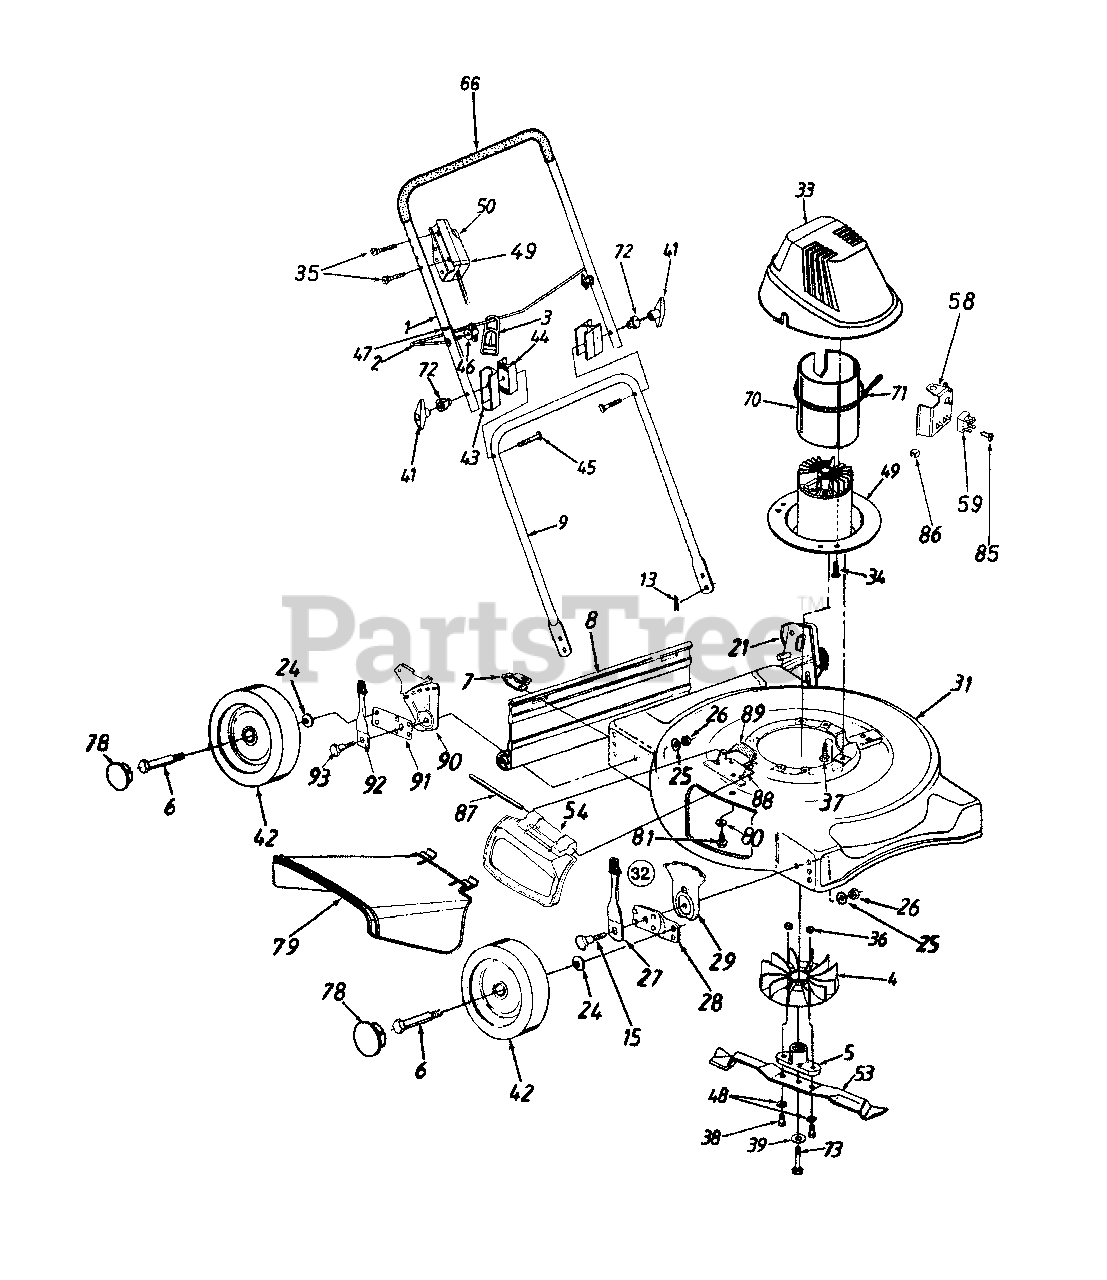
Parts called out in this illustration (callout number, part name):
3	Strain Relief Cord
5	Blade Adapter
6	Axle Bolt
7	Hinge Clip
8	Rear Flap
15	Shld. Bolt .5" Dia. x .434"
24	Spr. Washer .401 x .870 x .063
25	Bell Washer .39" I.D. x 1.38" O.D.
26	Hex Nut 3/8-16 Thd.
27	Spring Lever Assy. w/Knob
29	Height Adj. Plate
33	Motor Cover
34	Screw #10-16 x .75" Lg.
35	Oval C-Sunk Screw 1/4-20 x 1.81
36	Lock Nut 1/4-20 Thd.
37	Hex Lock Wash. TT-Tap Scr. 3/8-16 x .75"
38	Carriage Screw 1/4-20 x 6.5" Lg.
39	Bell Washer .396" I.D. x 1.14"
41	Plastic Knob
42	Wheel Assy. Comp. (8" x 1.75")
43	Upper Handle Insulator
44	Lower Handle Insulator
45	Carriage Bolt 5/16-18 x 3" Lg.
46	Wing Nut 1/4-20 Thd.
47	Cable Tie
48	Flat Washer .720 x .255 x .060
49	Motor, Cord & Switch Assy.
50	Switch Assembly.
53	18" Blade
58	Heat Sink Bracket
59	Rectifier: 35 Amp.
66	Foam Grip
70	Insulator
71	Cable Tie
72	Insulator Knob
73	Hex Bolt 3/8-24 x 2.5" Lg.
78	Hub Cap
79	Chute Deflector
80	Bell-Wash. 1/4" I.D.
81	Hex Wash. Hd. TT-Tap Scr. 1/4-20 x .5" Lg.
85	Insulator Wire Output
86	Insulator Wire Output
